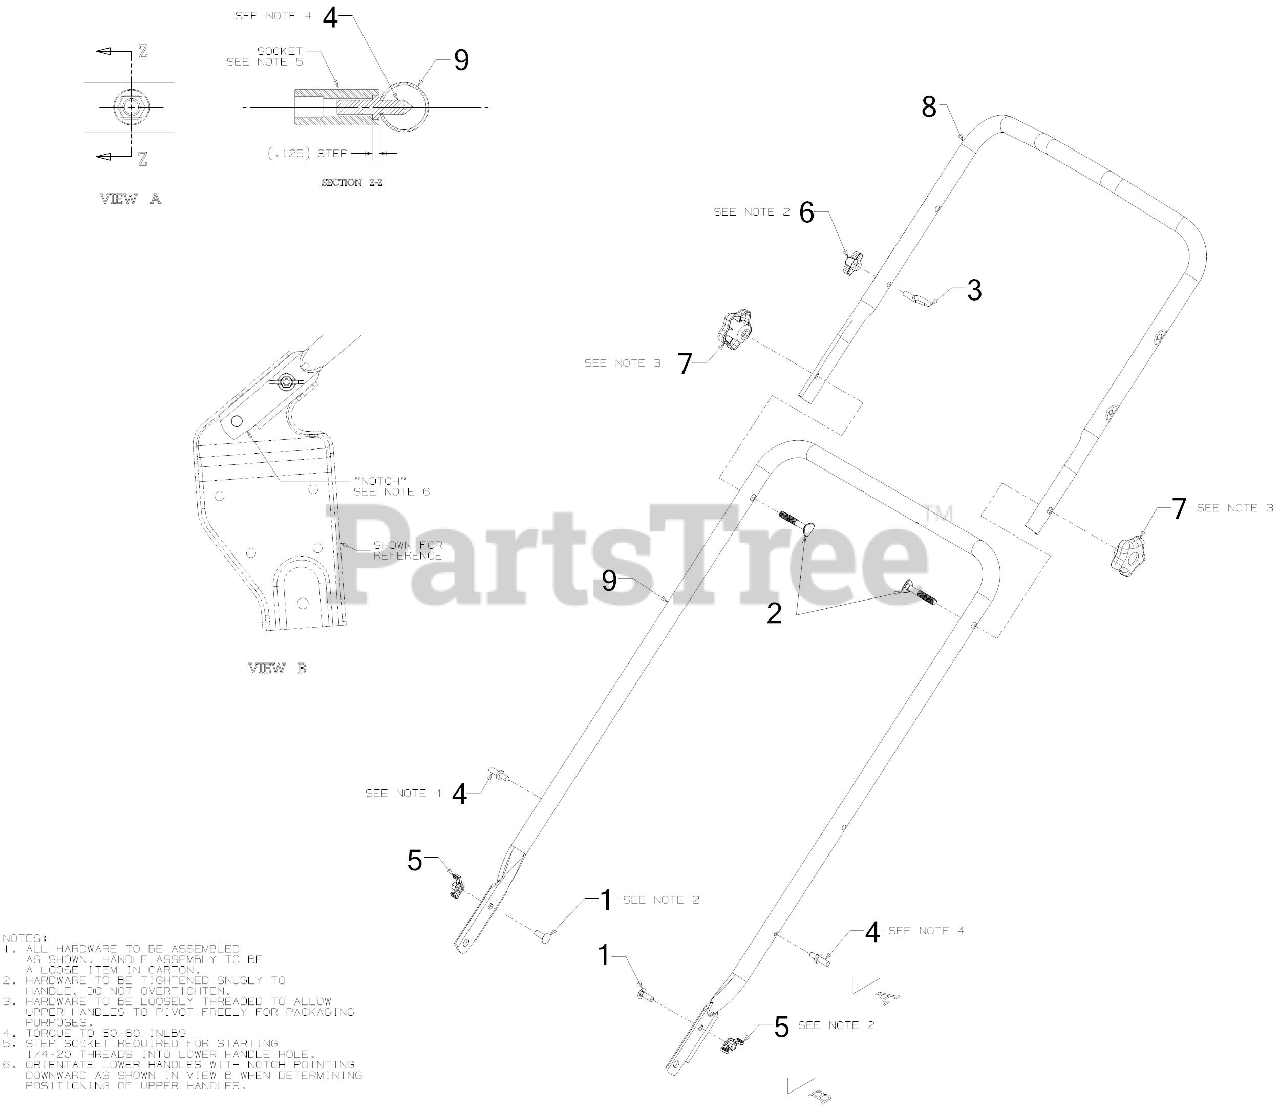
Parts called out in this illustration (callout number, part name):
1	SCREW 1/4-20 x .75 GR5
2	SCREW .312-18X2.0
3	EYEBOLT 1/4-20
4	BELT KEEPER PIN 1/4-20
6	HANDLE KNOB
7	STAR KNOB 5/16-18
8	UPPER GULLWING HANDLE
